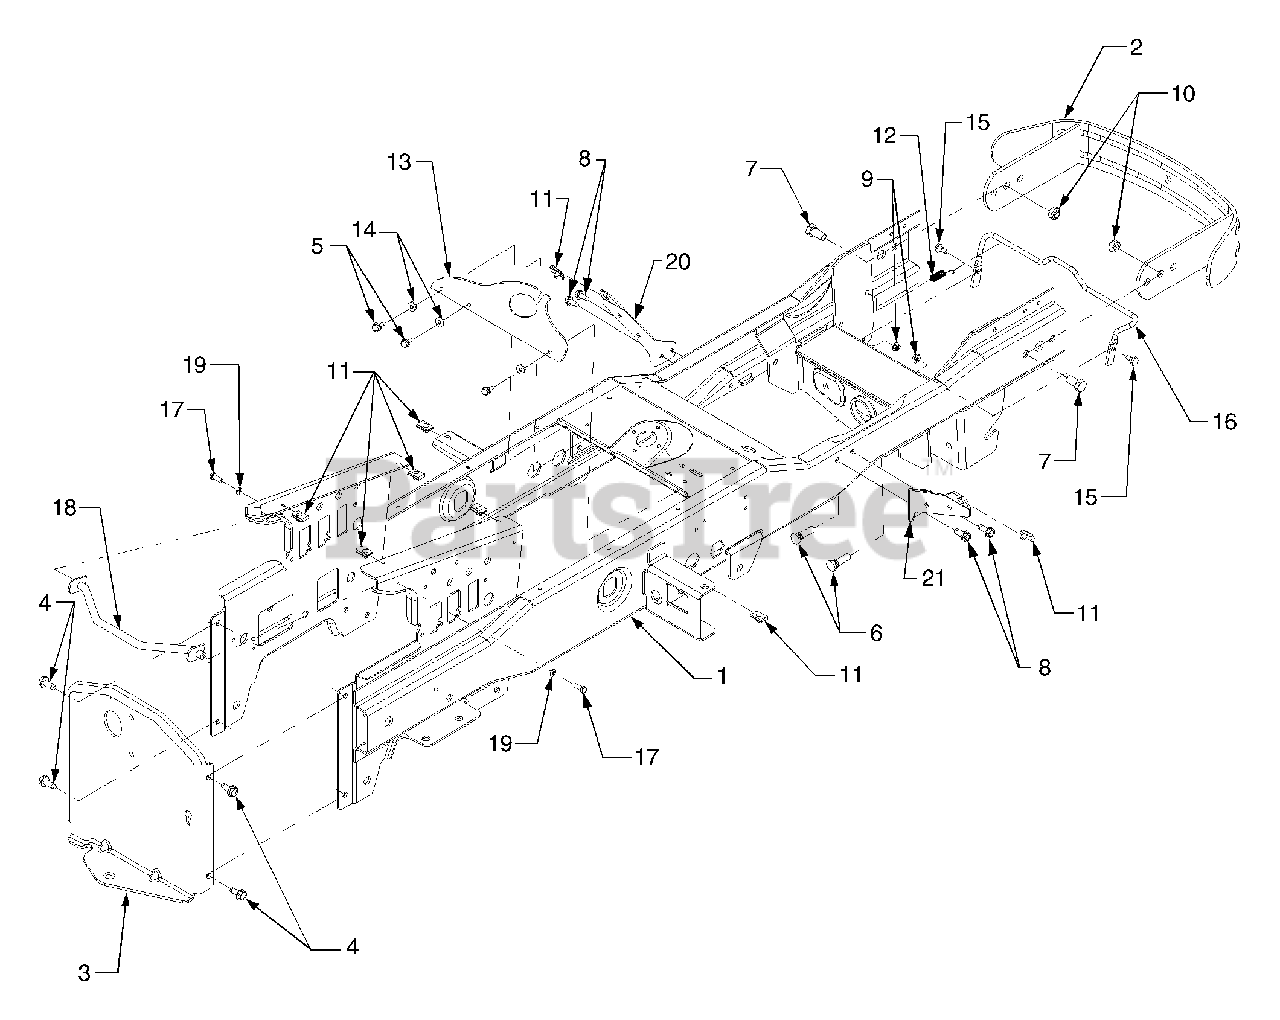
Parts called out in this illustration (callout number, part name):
1	Frame Assembly
2	Bumper, Front
4	Screw, Hex Wash. Hd. Tapp 3/8-16 x .7 5
5	Screw, Hex Wash. Hd. Tapp 1/4-20 x .5
6	Screw, Round Hd., 3/8-24
7	Screw, Hex Cap 1/2-13 x 1.0 GR5
8	Screw, Hex Wash. Hd. Tapp 5/16-18 x .75
9	Nut, Hex Flange Lock, 1/4-20
10	Nut, Hex Lock, 1/2-13
11	Speed Nut, U-Type, 5/16-18
12	Spring, Extension
13	Flap, Intk.
14	Washer, Flat, .283 x .75 x .030
15	Shoulder Screw, .312 x .18
16	Rod, Front Latch
17	Screw, Hex Cap, 1/4-20 x .75 GR5
18	Shaft, Tank Constraint
19	Washer, Lock, 1/4
20	Bracket, Running Board LH
21	Bracket, Running Board RH
